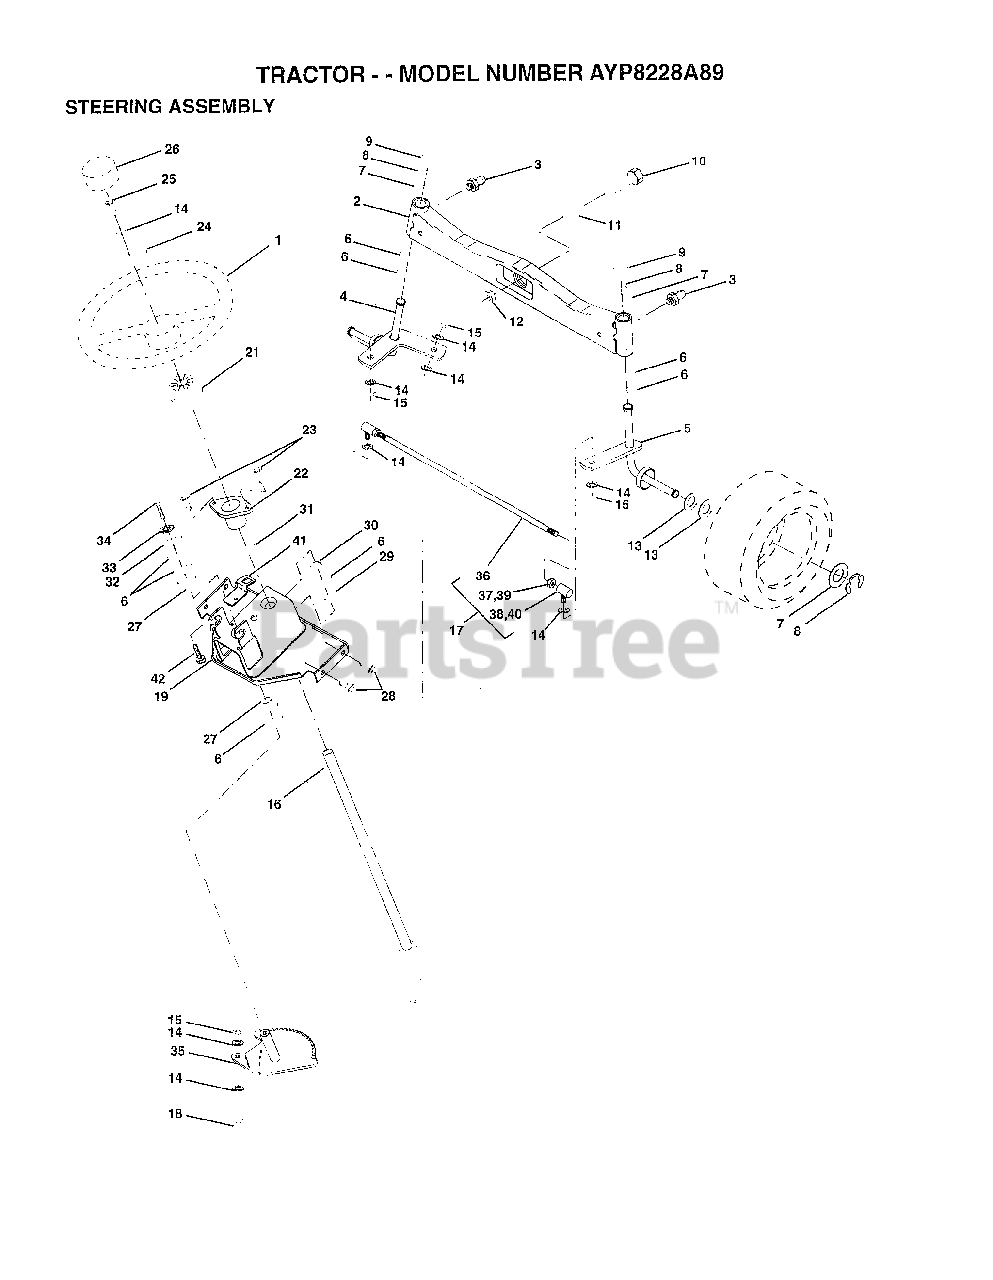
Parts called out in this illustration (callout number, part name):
3	ZERK M
4	SPINDLE ASM LH
5	SPINDLE ASM RH
6	WASHER .T
7	WASHER
8	RING
9	CAP
10	BOLT
11	SPACER BEARING
12	"NUT-LOC,FLANGE LT"
13	WASHER
14	LOCKWASHER
15	GRIPCO NUT
16	SHAFT.STEER.VGT
17	ROD.ASM.TIE.BALL
18	DRAGLINK.BALL.JOI
19	SUPPORT ASM-STEER
21	ADAPTER LT
22	"BUSHING,STEERING"
23	"SCREW-TT,10-32 FL"
24	WASHER T
25	BOLT
26	"INSERT,STR WHEEL"
27	COL. SRTG. BEAR.
28	SCREW
29	"FLANGE GT, BEAR."
30	KLIP RING
31	BUSHING.NYLINER.
32	WASHER
33	LOCKWASHER
34	BOLT
35	GEAR.ASM.SECTOR.
37	NUT
38	JOINT.RH
39	NUT
40	JOINT.LH
41	"BRKT-SW, INTER"
42	SCREW LT
